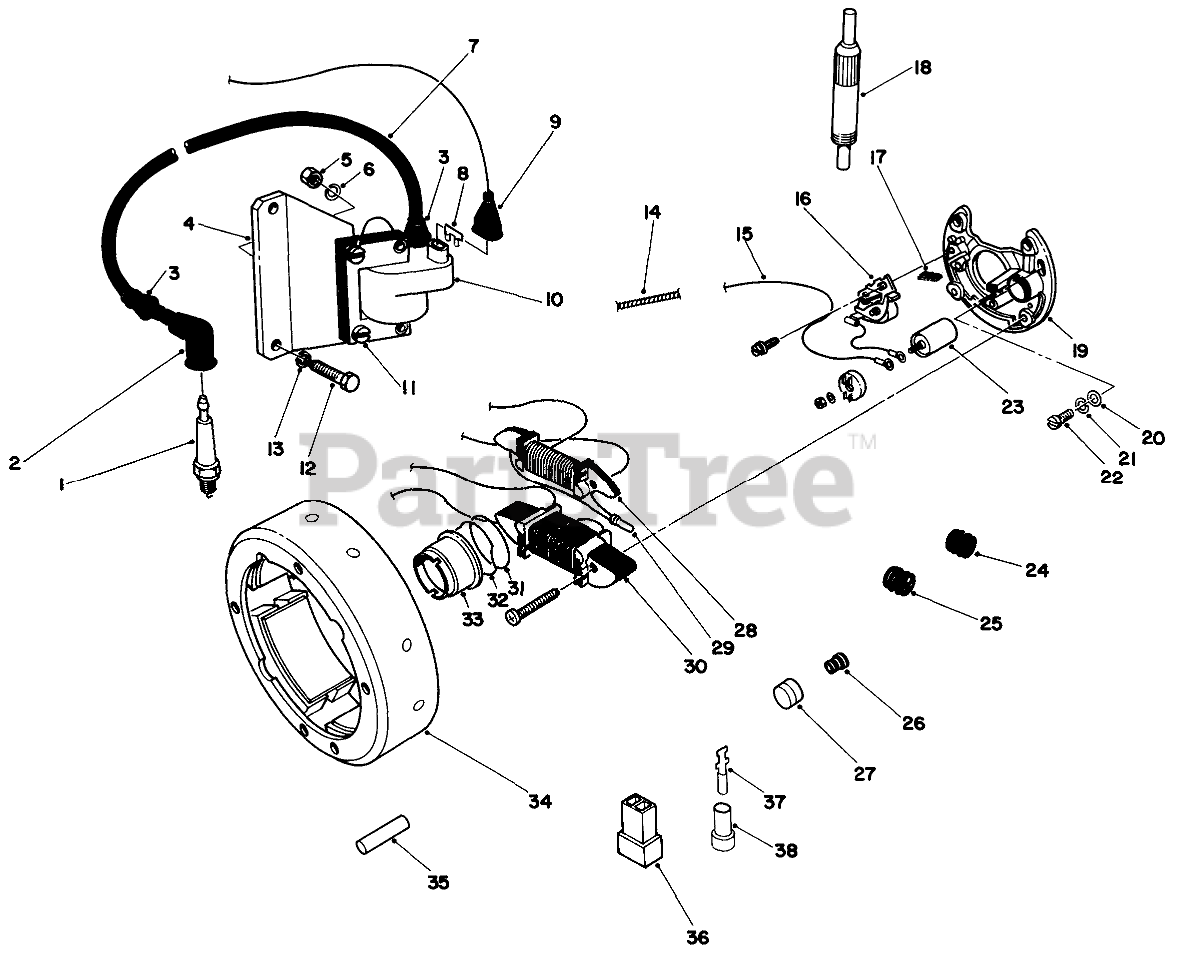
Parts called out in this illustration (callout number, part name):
1	Spark Plug
2	SPARK PLUG CAP
3	Rubber Socket
4	Bracket
6	Lockwasher
7	Cable-Ignition
8	Connector
10	Ignition Coil
11	Socket-Capscrew
12	Screw-Hex Head
13	Lockwasher
14	Spiral Band
16	POINT SET
17	Lubricating Wick
18	Gauge-Timing
19	Armature Plate Assembly
20	Washer
21	Lockwasher
22	Socket-Capscrew
23	Condenser
24	Grommet
25	Grommet
26	Grommet
28	Coil-Lighting
29	Connector
30	Lighting Coil
31	Washer
32	Locking Ring
34	Magnetic Flywheel
35	Sleeve
36	Connector
38	Connector
